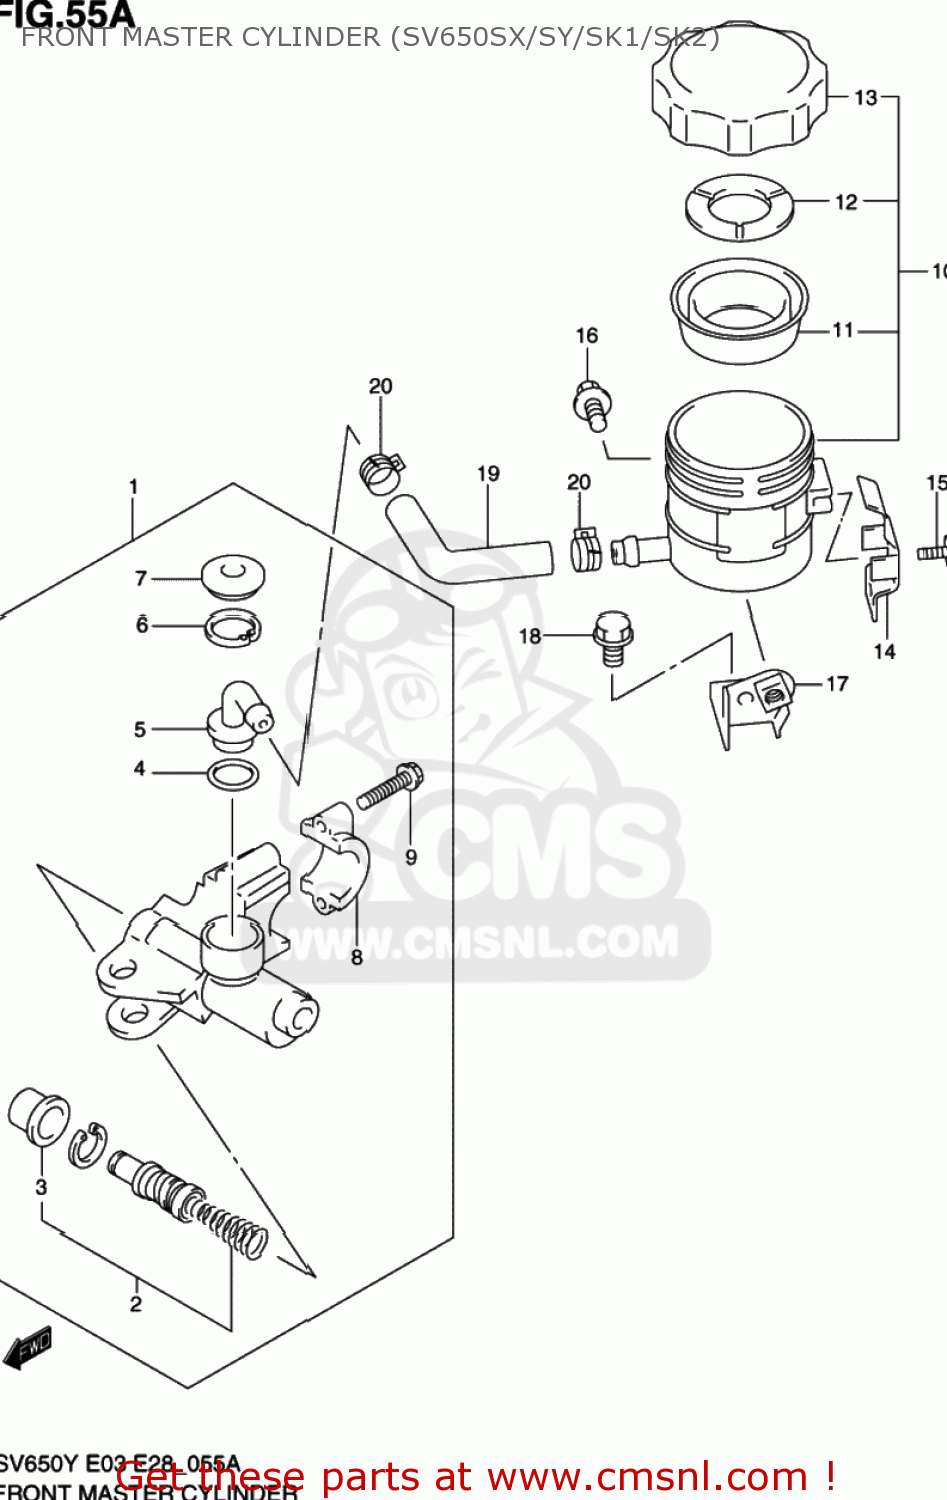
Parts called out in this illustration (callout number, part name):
1	CYLINDER ASSY,FR MASTER
2	PISTON & CUP SET
3	BOOT
4	O RING
5	CONNECTOR
6	CIRCLIP
7	COVER,DUST
8	HOLDER
9	BOLT(6X25)
10	TANK ASSY,RESERVOIR
11	DIAPHRAGM
12	PLATE,DIAPHRAGM
13	CAP
14	PLATE,RESERVOIR TANK CAP
15	SCREW
16	BOLT
17	BRACKET,RESERVOIR TANK
18	BOLT
19	HOSE,FR RESERVOIR TANK
20	CLAMP,RESERVOIR TANK FR
